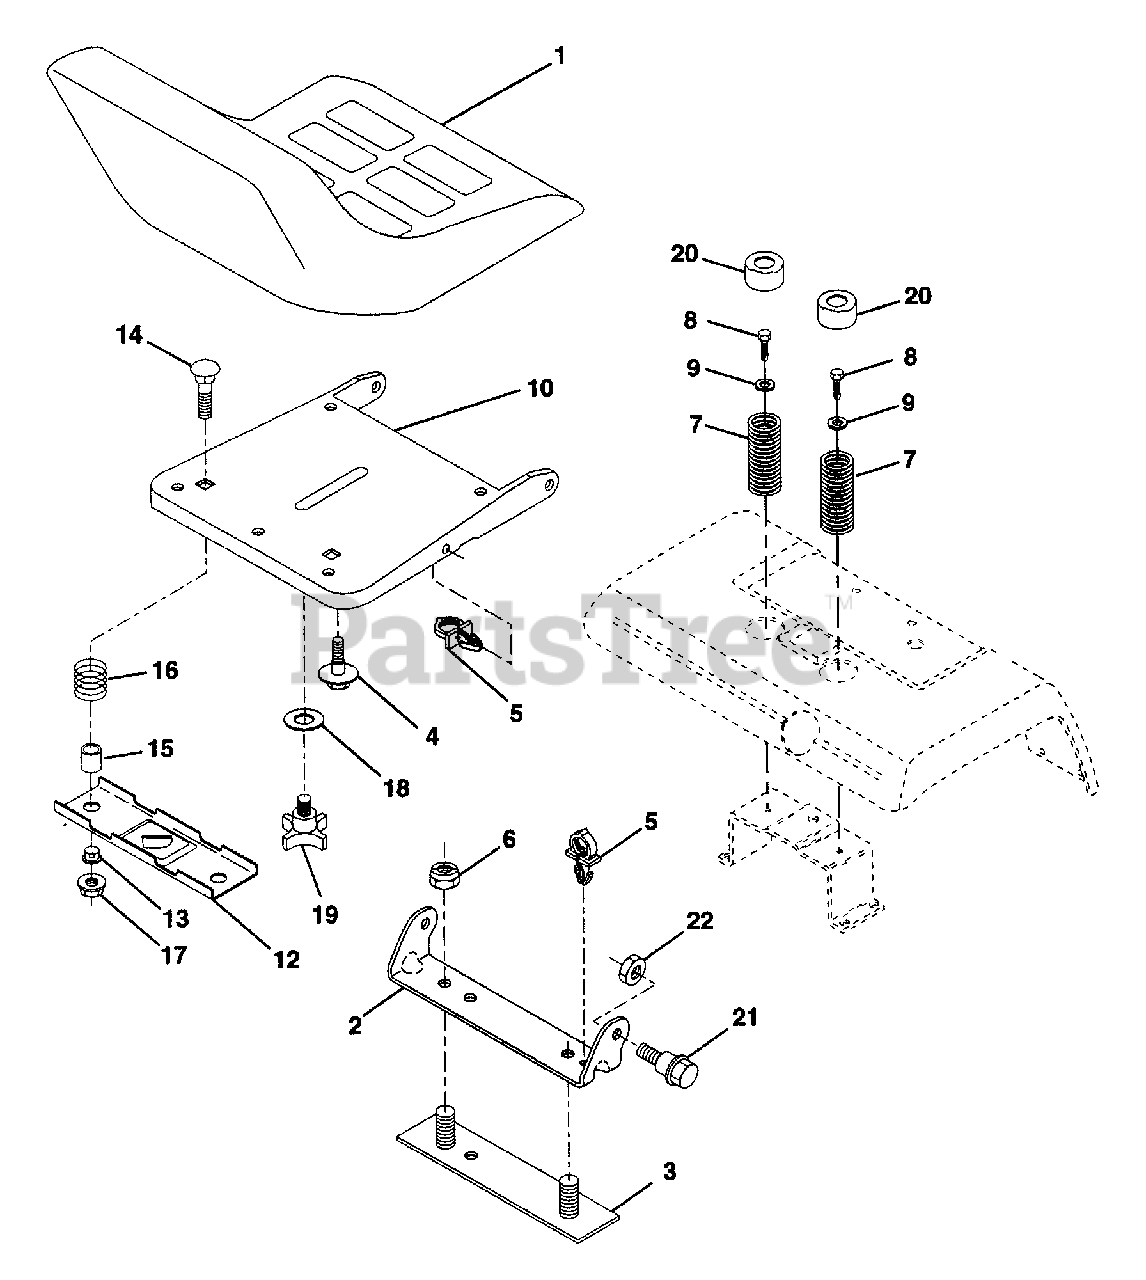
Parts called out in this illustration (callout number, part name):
1	Seat
2	Bracket, Pivot Seat
3	Strap, Fender
4	Bolt, Shoulder 5/16-18 X .62
5	Clip, Push In
6	Locknut 3/8-16 Unc
7	Spring, Seat Cprsn
8	Screw, Thdrol 5/16-18 X 1/2
9	Washer 13/32 X 1 X 14 Ga.
10	Pan, Seat
12	Bracket, Mounting Switch
13	Bushing, Snap
14	Bolt, Carriage 1/4-20 X 1-3/8
15	Spacer, Split
16	Spring, Cprsn
17	Nut, Lock 1/4 Lge FIg Gr. 5
18	Washer 17/32 X 1-3/16 X 12 Ga.
19	Knob, Seat 1/2-13 Unc
20	Cap, Spring Seat
21	Bolt, Shoulder 5/16-18 Unc
22	Nut, Crownlock 5/16-18 Unc
